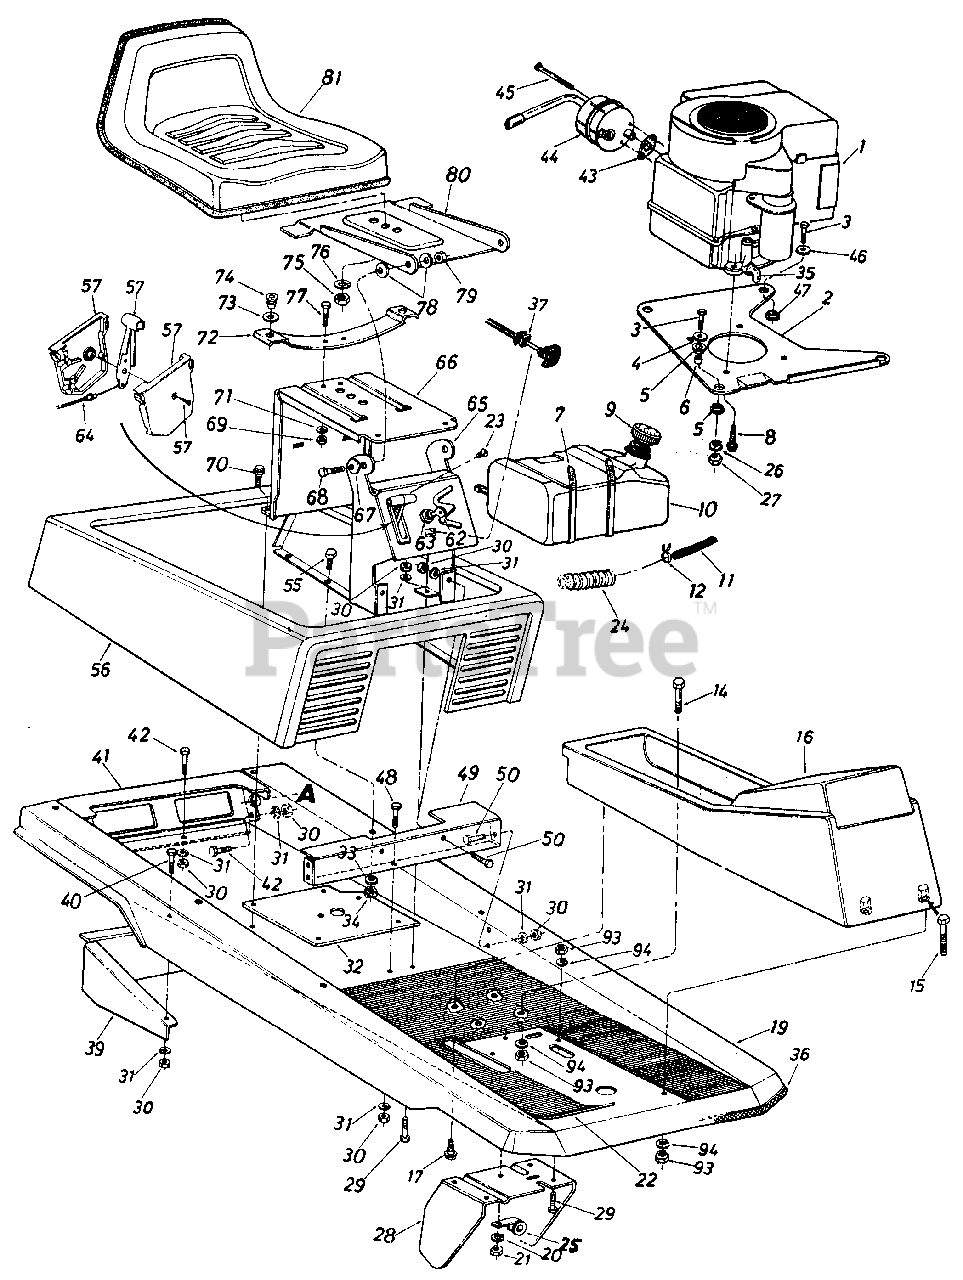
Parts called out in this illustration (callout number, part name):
1	Engine
2	Engine Mounting Plate
3	Hex Bolt 5/16-24 x 1.25" Lg.
4	Fl-Wash. .330" I.D. x 1.125" O.D.
5	Engine Mounting Grommet
6	Spacer .315" I.D. x .50" O.D. x .520" Lg.
7	Cable Tie 30.6 Lg.
8	Hex Wash. Hd. Self-Tap Scr. 3/8-16 x 1.25" Lg.
10	Fuel Tank
11	Gas Line
12	Hose Clamp-.406" Dia.
14	Hex Bolt 5/16-18 x 1.75" Lg.
15	Hex Bolt 5/16-18 x 2.0" Lg.
16	Front Console
17	Plastite Scr. 5/8 x 1.25"
19	Main Frame
20	L-Wash. 5/16" I.D.*
21	Hex Nut 5/16-18 Thd.
23	Truss Mach. AB-Tap Scr. #10 x .50" Lg.
24	Convoluted Conduit
26	L-Wash. 5/16" I.D.
27	Hex Nut 5/16-24 Thd.
28	Clutch-Brake Pedal Ass'y.
29	Hex Bolt 5/16-18 x .75" Lg
30	Hex Nut 5/16-18 Thd.
31	L-Wash. 5/16" I.D.
32	Mounting Brkt. Variable Speed Pulley
33	L-Wash. 1/4" I.D.
34	Hex Nut 1/4-20 Thd.
35	90ø Elbow Male To Female
36	Trim Strip 18" Lg.
37	Choke Control
39	Transaxle Support Ass'y.
40	Hex Bolt 5/16-18 x .75" Lg.*
43	Exhaust Gasket
44	Muffler Ass'y.
45	Shld. Bolt
46	Fl-Wash. .330" I.D. x 1.25" O.D.
47	Flange Wash. .320" I.D. x .750" O.D.
49	Seat Support & Frame Brkt.
50	Hex Bolt 5/16-18 x .75" Lg.*
55	Hex Bolt 1/4-20 X .50" Lg.*
56	Engine Cover Ass'y.
57	Throttle Control Box Ass'y.
62	Ignition Key
63	Ignition Switch
64	Throttle Control Wire
65	Front Seat Bracket
66	Rear Seat Bracket
67	Bell-Wash. .345" I.D. x .88" O.D.
68	Hex Bolt 5/16-18 x .75" Lg.*
69	Hex Nut 5/16-18 Thd.*
70	Hex Self-Tap Scr. 5/16-18 x .75" Lg.
71	L-Wash. 1/4" I.D.*
72	Seat Spring
73	Fl-Wash. .531" I.D. x .930" O.D.
74	Grommet
75	Hex Nut 1/2-13 Thd.*
76	L-Wash. 1/2" I.D.*
77	Hex Bolt 1/4-20 X .75" Lg.*
78	Bell-Wash. .345" I.D. x .88" O.D.
79	Hex Cent. L-Nut 5/16-18 Thd.
80	Seat Pivot Bracket
81	Seat Ass'y. Comp.
93	Hex Nut 5/16-18 Thd.*
94	L-Wash. 5/16" I.D.*
